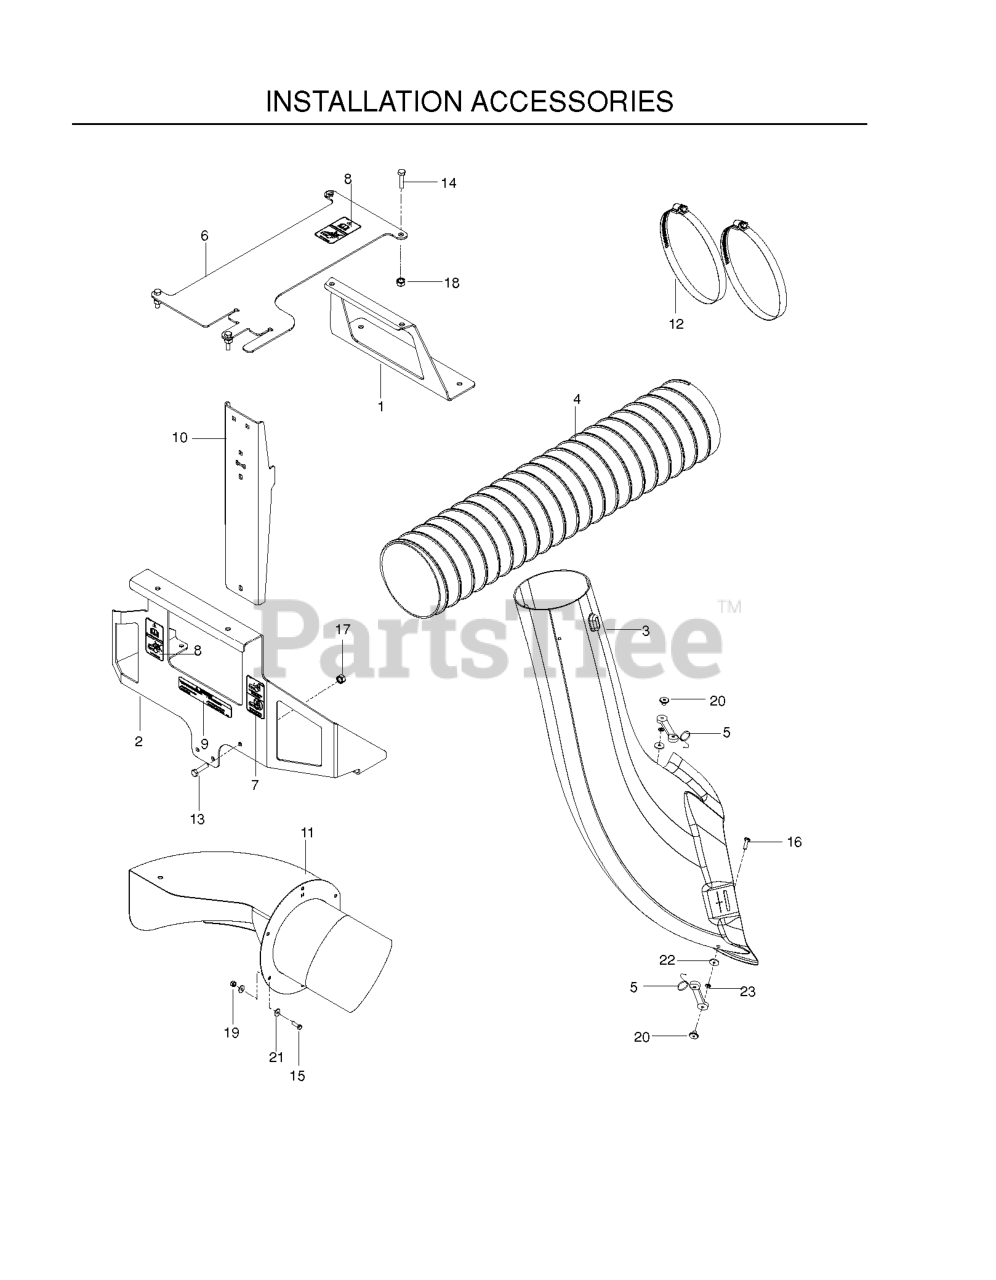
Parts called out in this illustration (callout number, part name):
1	FRT BRACKET TOOL BOX, PAINTED
2	REAR BRACKET W/ DECALS
3	CHUTE.LOWER.LT.46"
4	HOSE, 6-3/4 ID X 26
5	LATCH ASSY TBR
6	PLATE, W/DECAL
7	DECAL, PAYLOAD/GASOLINE
8	DECAL, UTILITY BOX WARNING
9	DECAL, UTILITY BOX PAYLOAD
12	HOSE CLAMP 4-1/8 TO 7"
13	HCS 5/16C X 3/4
14	SCREW 3/8C X 3/4 HEX CAP
15	HCS 1/4C X 3/4 HCS
16	SCREW #10-24 X 5/8
17	NUT 5/16 NYLOC
18	NUT 3/8-16 NYLOC
19	NUT.1/4-20.HEX.NYLOC.ZD
20	NUT 10-24 WELD PLATED
21	WASHER 1/4 FLAT
23	WASHER - 3/16 LOCK ZD
